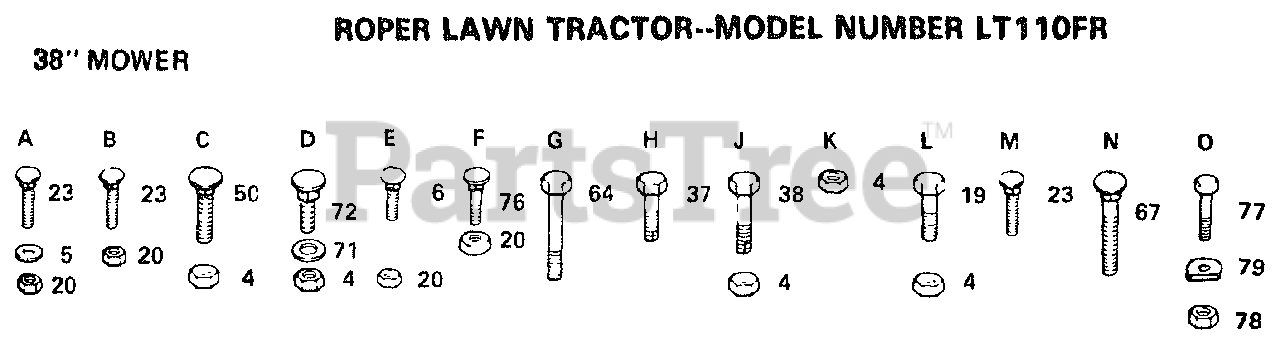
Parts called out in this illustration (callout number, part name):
5	WASHER M
6	BOLT
23	BOLT
37	SCREW
38	SCREW
50	BOLT
67	BOLT.3/8-14X1.25
71	WASHER
72	BOLT
79	WASHER T
